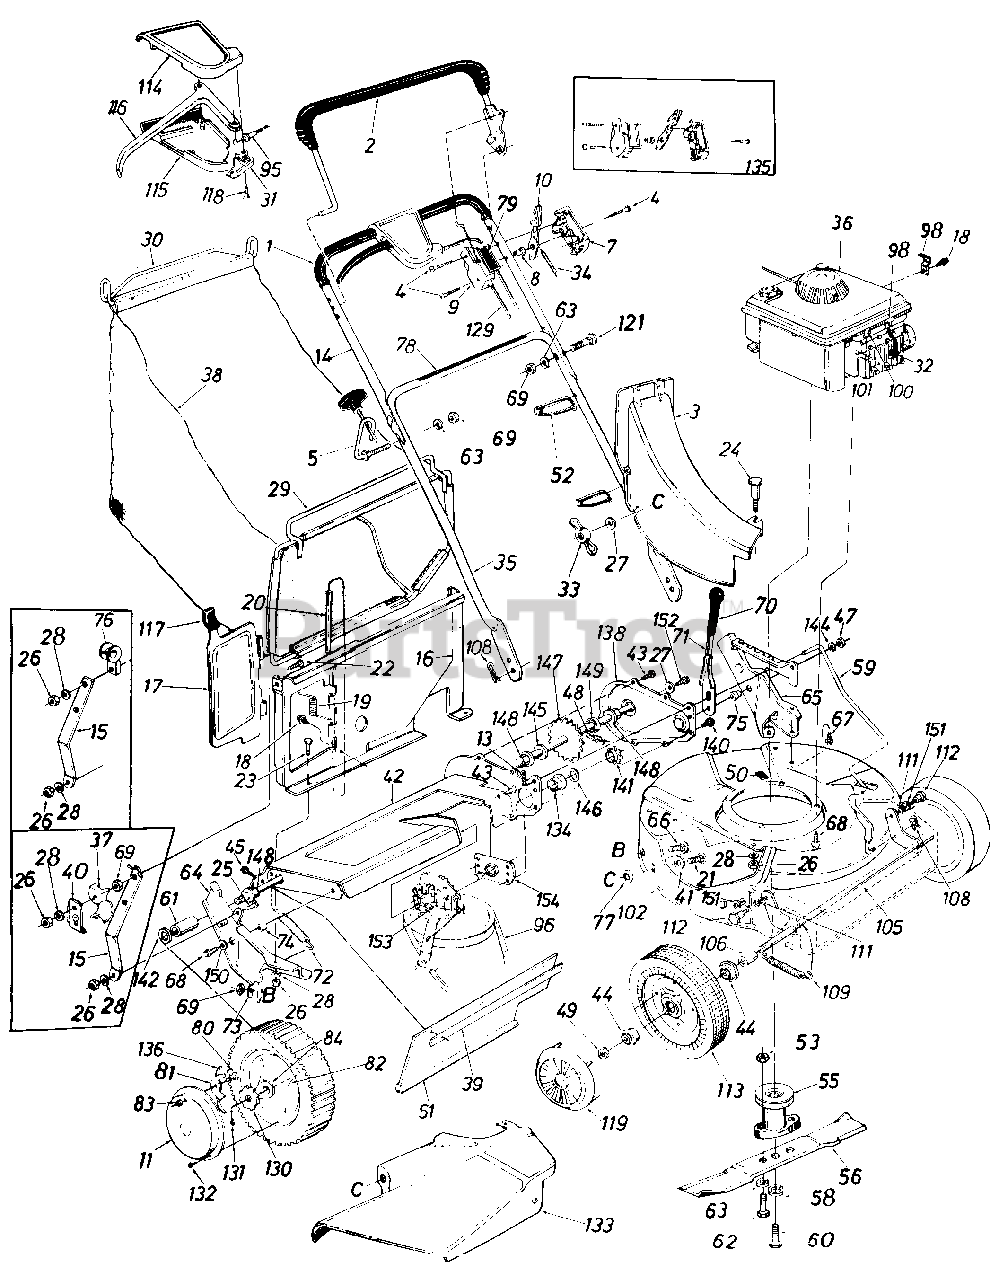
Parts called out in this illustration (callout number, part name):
2	Control Handle Ass'y.-L.H.
3	Top Discharge Chute Ass'y.
4	Truss Mach. Scr. #12 x 1.50" Lg.
5	Rope Guide Bolt
7	Control Panel Half
8	Control Disc Pin
9	Clutch Panel Half
10	Throttle Control Lever
11	Hub Cap
13	Cotter Pin 3/32" Dia. x .75"*
14	Upper Handle-Chrome
15	Panel Support Brkt.
16	Top Catcher Panel
17	Top Door
18	Hex B-Tap Scr. #10 x .38"
19	Torsion Spring
20	Pivot Pin
21	Carriage Bolt 1/4-20 x .62"*
22	Truss Mach. Scr. 1/4-20 x 3/4" Lg
23	Hex Bolt 1/4-20 x .50" Lg.*
24	Shoulder Bolt .312 Dia. x .18 Lg. Special
25	Hex Bolt 1/4-20 x .62" Lg.*
26	Hex Nut 1/4-20 Thd.*
27	Bell-Wash. 1/4" I.D.
28	L-Wash. 1/4" I.D.*
29	Front Grass Catcher Frame
30	Grass Catcher Handle
31	S.P. Control Cover
32	Spark Plug Insulator
33	Wing Nut
34	Throttle Control Wire 58"
35	Lower Handle-Chrome
36	Engine
37	Rope Guide Half
38	21" Top Discharge Grass Bag
39	Retaining Strip
40	Rope Retainer Spring Clip
41	Fl-Wash. .344" I.D. x .62"
42	Chain-Axle Ass'y.
43	Hex B-Tap Scr. 1/4" x .38" Lg.
44	Flange Ball Bearing 1/2" I.D.
45	Hex AB-Tap Scr. 1/4 x .62"
47	Hex Patch L-Nut 3/8-24 Thd.
48	#48 Chain .500" Pitch x .30 Links
49	Hex L-Nut 1/2-20 Thd.
51	Rear Flap 3.75" x 17.30" Lg.
52	Cable Tie
53	Hex Nut 5/16-24 Thd.*
55	Blade Adapter w/Pulley
56	21" Blade
58	Bell-Wash. .39" I.D. x 1.380" O.D.
59	Height Adj. Rod 19.42" Lg.
60	Hex Bolt 3/8-24 x 2.25" Lg. (Grade 5)
61	Spacer .513" I.D. x .703" O.D. x .69" Lg.
62	Hex Bolt 5/16-24 x 1.00" Lg. (Grade 5)
63	L-Wash. 5/16" I.D.
64	R.H. Handle Wheel Brkt. Ass'y.
65	L.H. Handle Wheel Brkt. Ass'y.
66	Carriage Bolt 5/16-18 x .62"
67	Hex Wash. Hd. B-Tap Scr. 5/1 6-1 8
68	Hex Wash. Hd. TT-Tap Scr. 3/8-1 6
69	Hex Nut 5/16-18 Thd.
71	Height Adj. Lever
72	Extension Spring .50" O.D. x 3.80" Lg.
73	Bell-Wash. 5/16" I.D.
74	Spacer .385" I.D. x .502" O.D. x .270" Lg.
75	Shld. Spacer 500" Dia. x . 1 00
76	Rope Guidet
77	Bolt Retainer 1/4 x .50" O.D.
78	Instruction Label
79	Control Label
80	Shld. Scr. .342" Dia. x .268
81	Pawl
82	Wheel Ass'y. Comp.-Rear 8x 1.75
83	Hex Ins. L-Nut 1/4-20 Thd.
84	Flange Ball Bearing 1/2" I.D.
95	S.P. Cable x 50" Lg.
96	"V"-Belt
98	Casing Clamp
100	Hex B-Tap Scr. #10 x .62"
101	Casing Clamp
106	Sleeve .526" I.D. x .690" O.D. x .880" Lg.
108	Intern. Cotter Pin 5/16" Dia.
109	Extension Spring .50" O.D. x 3.20" Lg.
111	Intern. L-Wash. 3/8 I.D.
112	Shld. Bolt .623" Dia. x .425
113	Front-Wheel Ass'y. Comp. 7 x 1.50
114	Self-Propelled Control Cover
115	Self-Propelled Control Cover
116	Control Lever
117	Door Grip
118	Fl-"C"-Sunk Hd. Tap Scr. #10 x .75" Lg.
119	Hub Cap-Plastic
121	Curved Carr. Bolt 5/16-18 x 1.38" Lg.
129	Control Cable-43" Lg.
130	Ratchet Wheel 1.62" O.D.
131	Cotter Pin 1/8" Dia. x 1.00" Lg.*
132	Pan Hd. Tap Scr. #12 x .50" Lg.
133	Side Chute Deflector Ass'y
134	Flange Bearing
135	Kit-Control Housing Comp.
136	Spring-Nylon
138	Chain Cover
140	Hex Wash. S-Tap Scr. 1/4-20 x.50" Lg.
141	Sprocket-Shaft Ass'y.
142	Fl-Wash. .510" I.D. x 1.0" O.D.
144	Fl-Wash. .385" I.D. x .87" O.D.
145	Fl-Wash. .51" I.D. x 1.0" O.D.
146	Fl-Wash. 3/8" I.D.
147	Rear Shaft Ass'y. 21.94" Lg.
148	Hex Flange Bearing .506" I.D. Plastic
149	Fl-Wash. .531" I.D. x .930" O.D.
150	Fl-Wash. .531" I.D. x 1.25" O.D.
151	Flanged Nyliner Brg.
152	Hex Bolt 1/4-20 x .62" Lg. (Grade 5)
153	Transmission Comp.
154	Hex Bearing Cup
